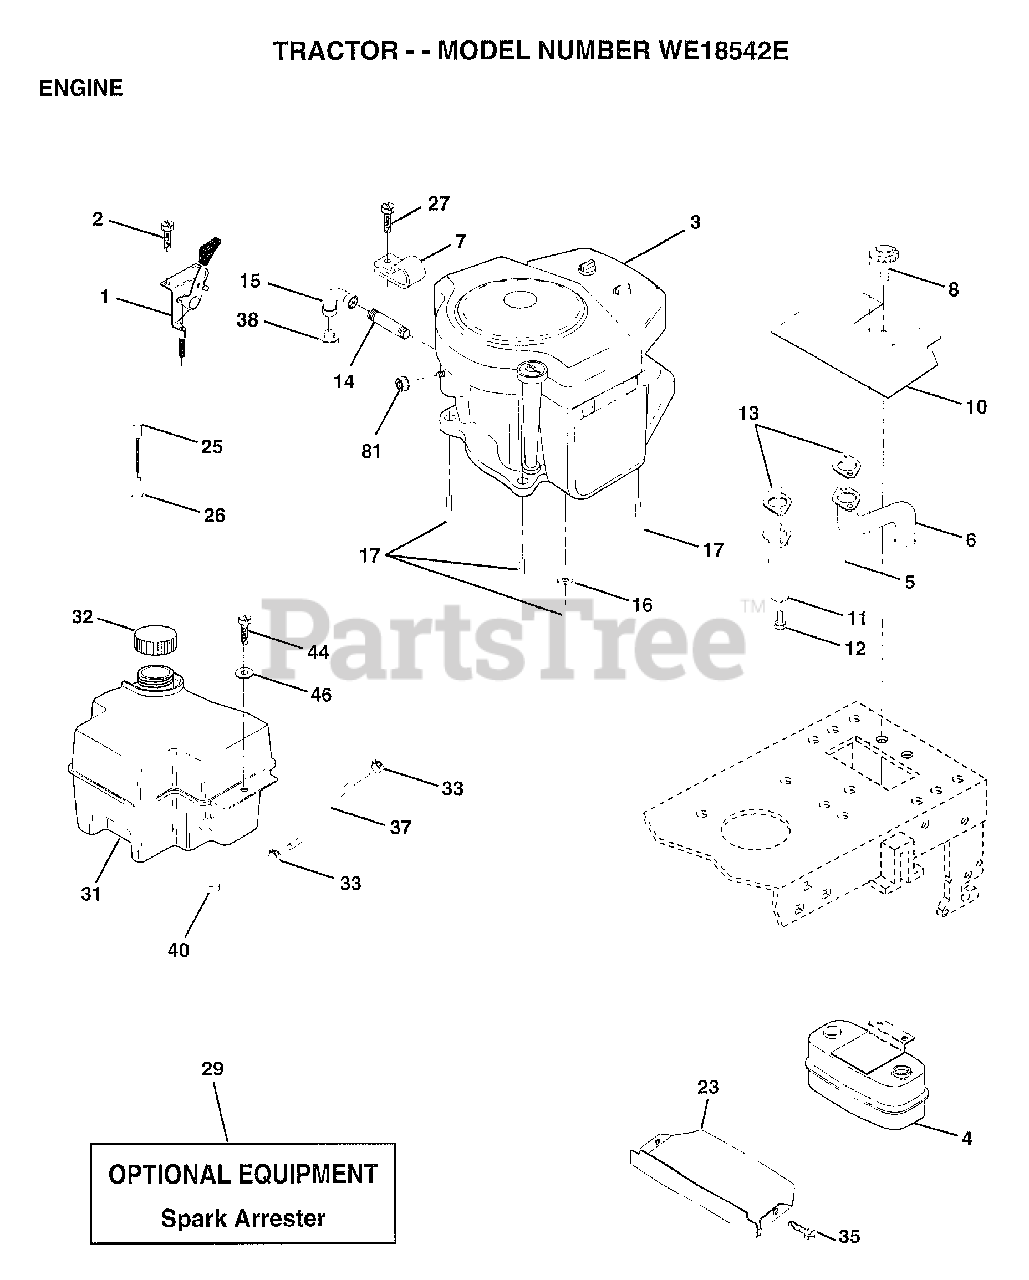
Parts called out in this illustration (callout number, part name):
1	CONTROL THRT 35.5
2	SCREW LT
4	MUFFLER.TW.LOTONE
5	EXHAUST.B&S.18.LH
6	EXHAUST.B&S.18.RH
7	CLAMP.TUBE.DBL.EN
8	BOLT.5/16-18.UNC
10	SHIELD.HEAT.
11	LOCKWASHER
13	GASKET MUFFLER
14	PIPE NIPPLE LT
15	ELBOW
16	LOCKWASHER
17	SCREW LT
23	SHIELD.BRN/DBR.GD
25	CONTROL.CHOKE.37
26	"NUT,KEPS 3/8-24IM"
27	"SCREW-TT,10-32 FL"
31	TANK.FUEL.FRONT.
32	CAP ASM FUEL
33	HOSE CLAMP
35	SCREW
37	LINE FUEL
44	SCREW HEX CRT
46	WASHER
81	NUT
